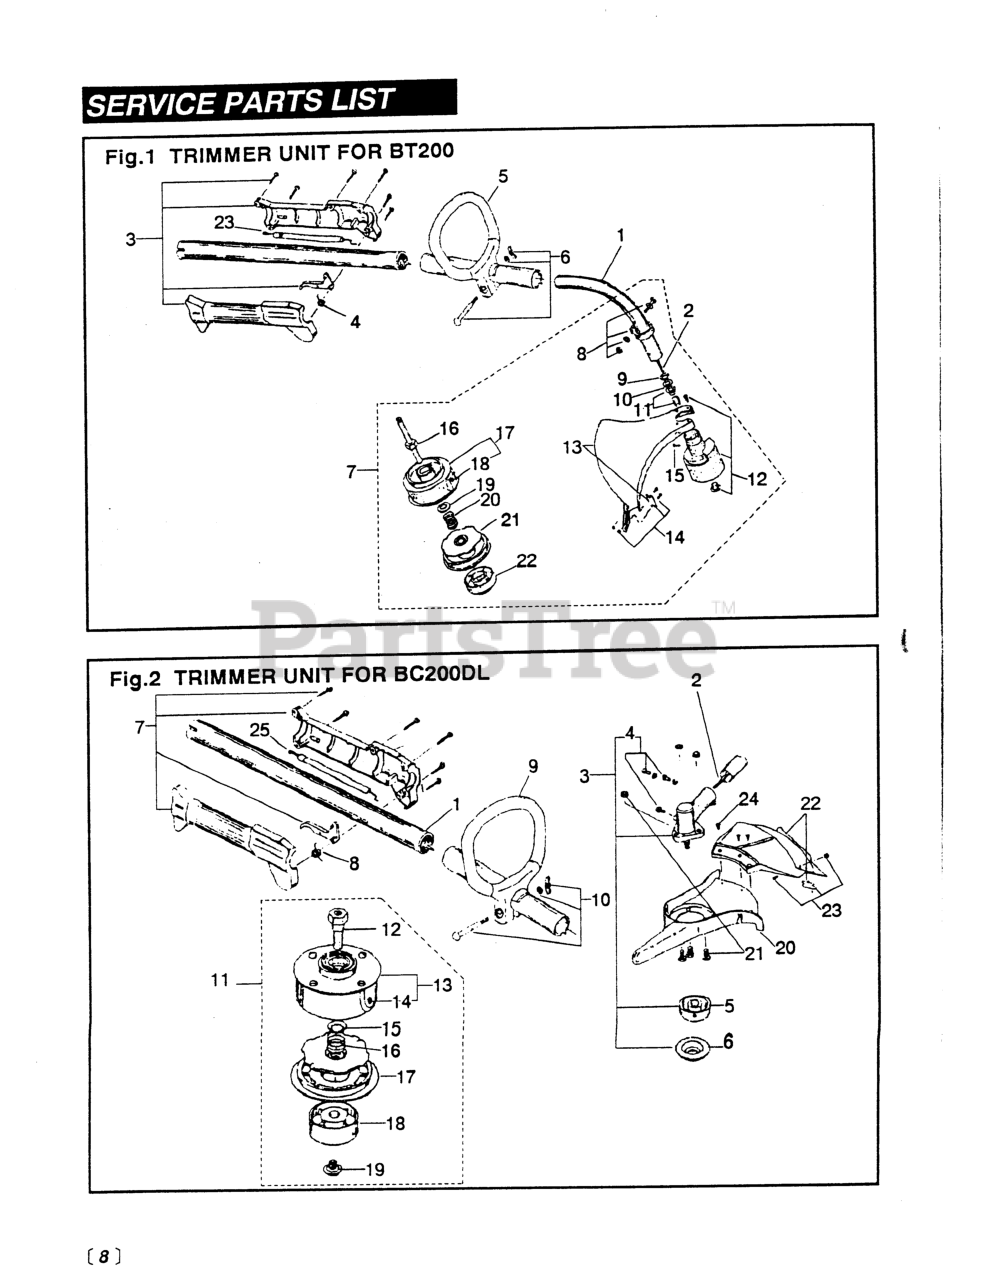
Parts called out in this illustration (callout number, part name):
1	SHAFT ASSEMBLY (BT)
4	SPRING, THROTTLE TRIGGER
7	CUTTING HEAD ASSEMBLY
8	CLAMP ASSY, LOWER
9	RING, RETAINING
10	WASHER
11	ASSY, BUSHING HOUSING
12	SCREW, GUARD MTG (SET)
14	BLADE ASSEMBLY
15	SET SCREW, ANTI-ROTATION
17	OUTER SPOOL ASSEMBLY
18	EYELET
19	WASHER, EYELET
